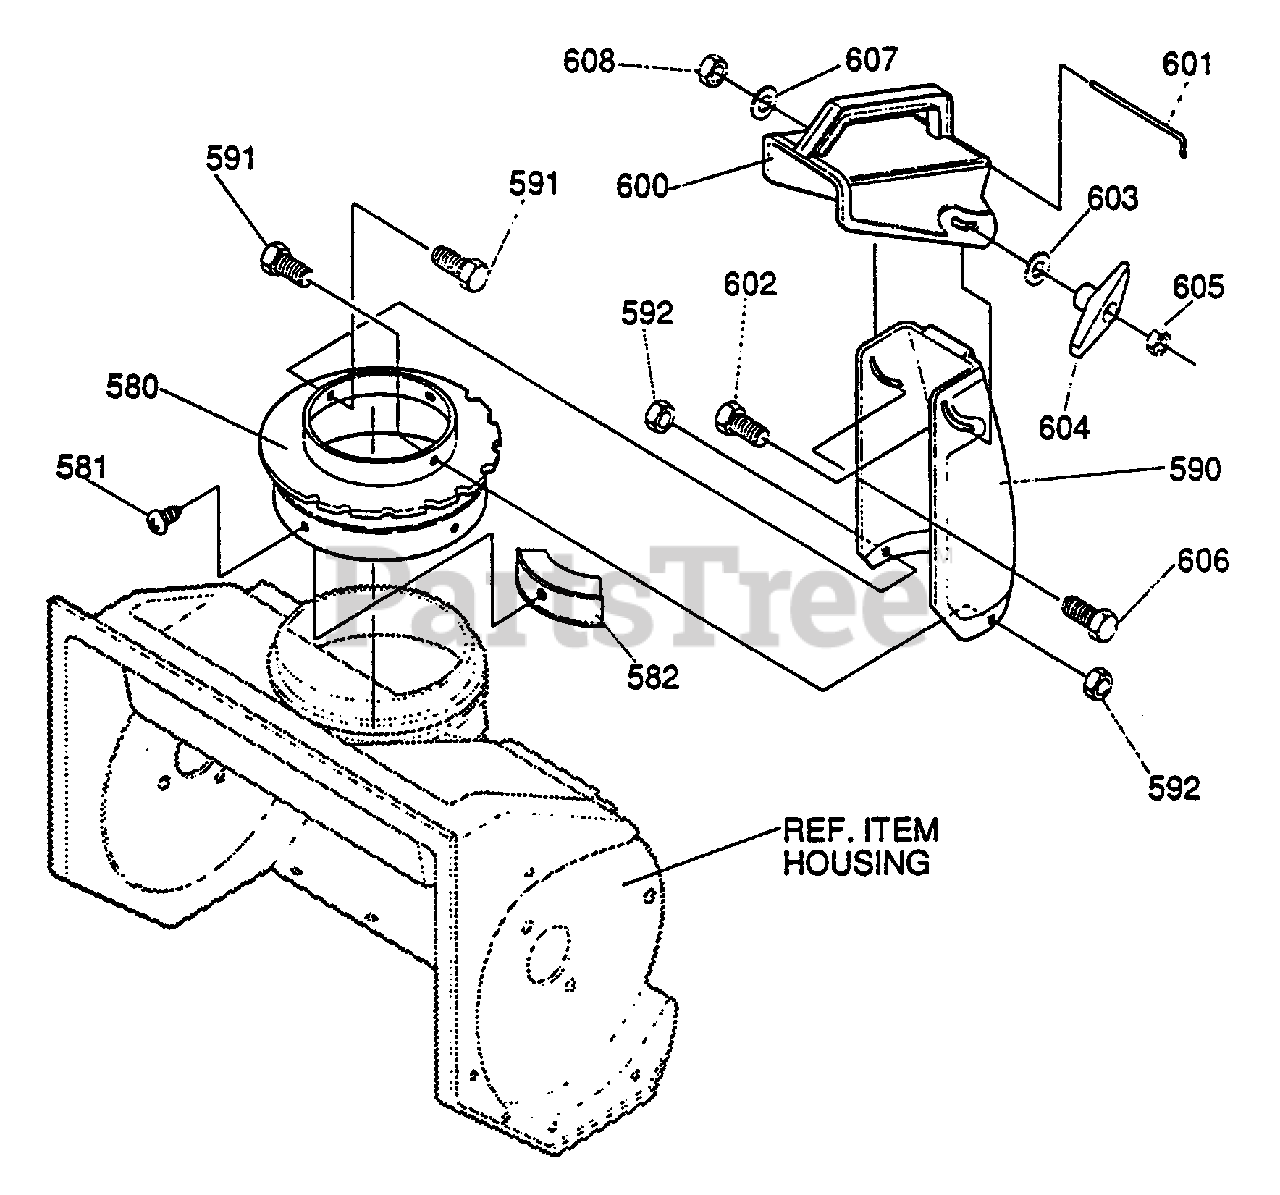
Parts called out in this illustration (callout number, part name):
580	RING, CHUTE
581	SCREW, 10-14 X .50
582	GUIDE, CHUTE
590	CHUTE, LOWER
591	SCREW, 1/4-20 X .50
592	NUT, 1/4-20 MAC-LOCK
600	CHUTE, UPPER
601	WIRE, HINGE
602	BOLT, 5/16-18 X 1.25
603	FLATWASHER .344 X .69 X .065
604	KNOB, T W/NUT
605	NUT, 5/16-18 REG HEX
606	SCREW, 5/16-18 X .75
607	FLATWASHER .344 X .69 X .065
608	NUT, 5/16-18 REG HEX CTRLK
